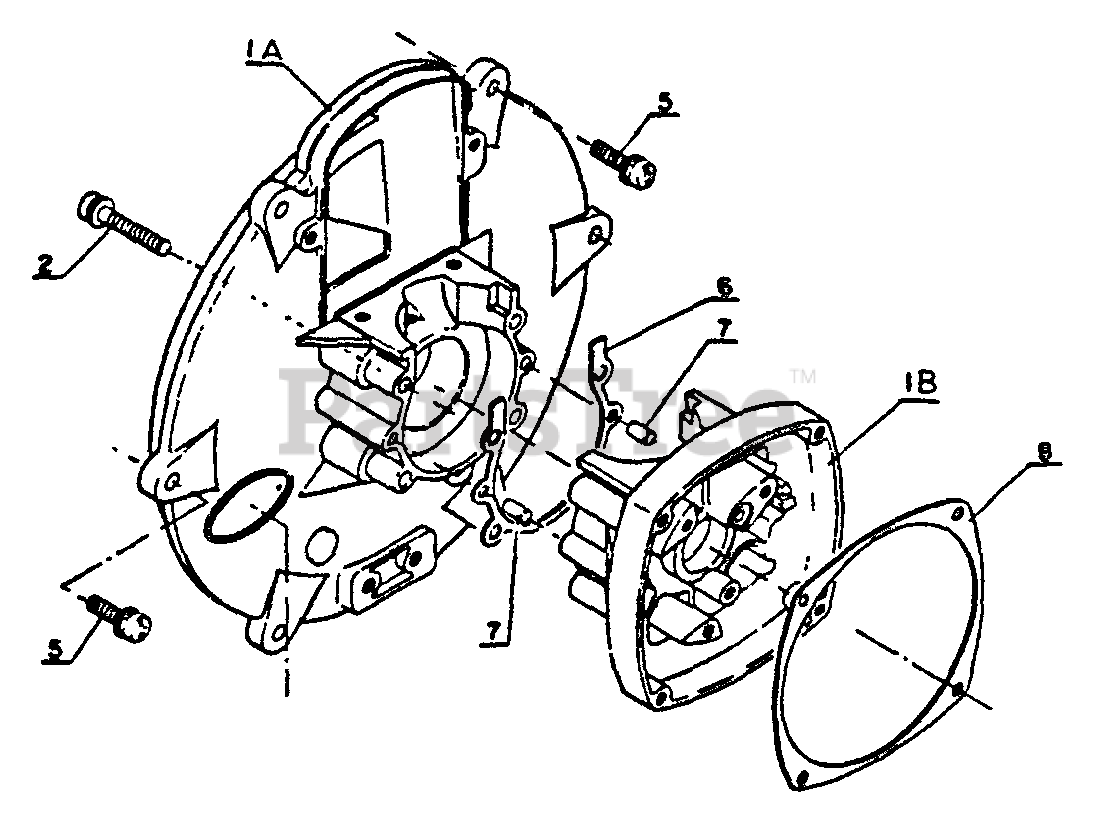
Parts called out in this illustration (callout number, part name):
1	CRANKCASE KIT
2	SCREW - 5X28
5	SCREW - 5X18
6	GASKET, CRANKCASE
7	PIN - LOCATING
8	GASKET, STARTER
